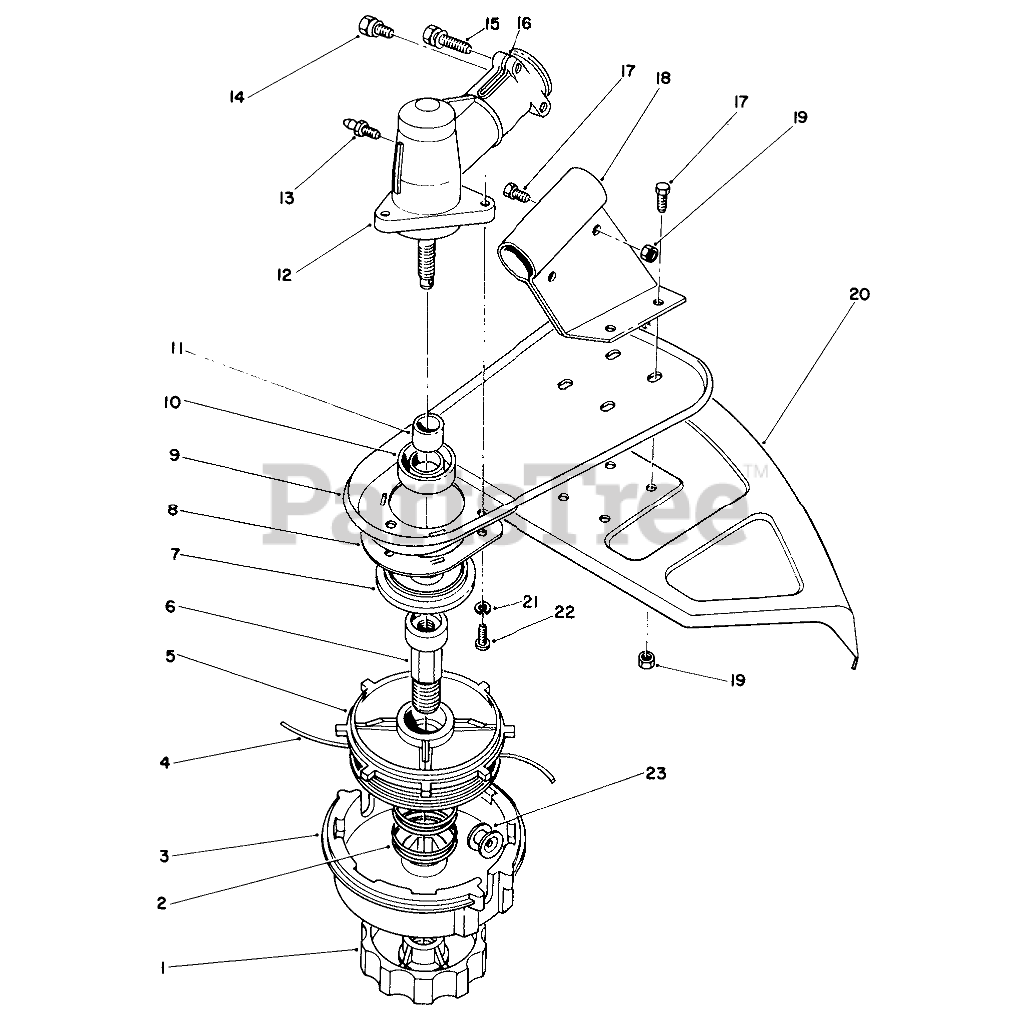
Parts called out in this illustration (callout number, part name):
1	LH KNOB(SERVICE ONLY)
2	SPRING (SERVICE)
3	SPOOL HSG (SERVICE ONLY
4	REPL LINE PKG
5	INNER SPOOL(SERV ONLY)
6	SHAFT (SERVICE ONLY)
7	DUST CAP F/W
8	GRASS WRAP GUARD
9	SHIELD SUPPORT R
10	OIL SEAL
11	SPLINED SLEEVE
12	Gear Box Assembly (Incl. Ref. #10, 11, & 13-16)
14	HHMS SCREW
15	HHMS SCREW
16	WASHER
17	SCREW-SHH
18	SHIELD BRKT
19	NUT-LOCK, NI
20	GRASS SHIELD R
21	LOCKWASHER
22	SCREW
23	EYELET(SERVICE)
